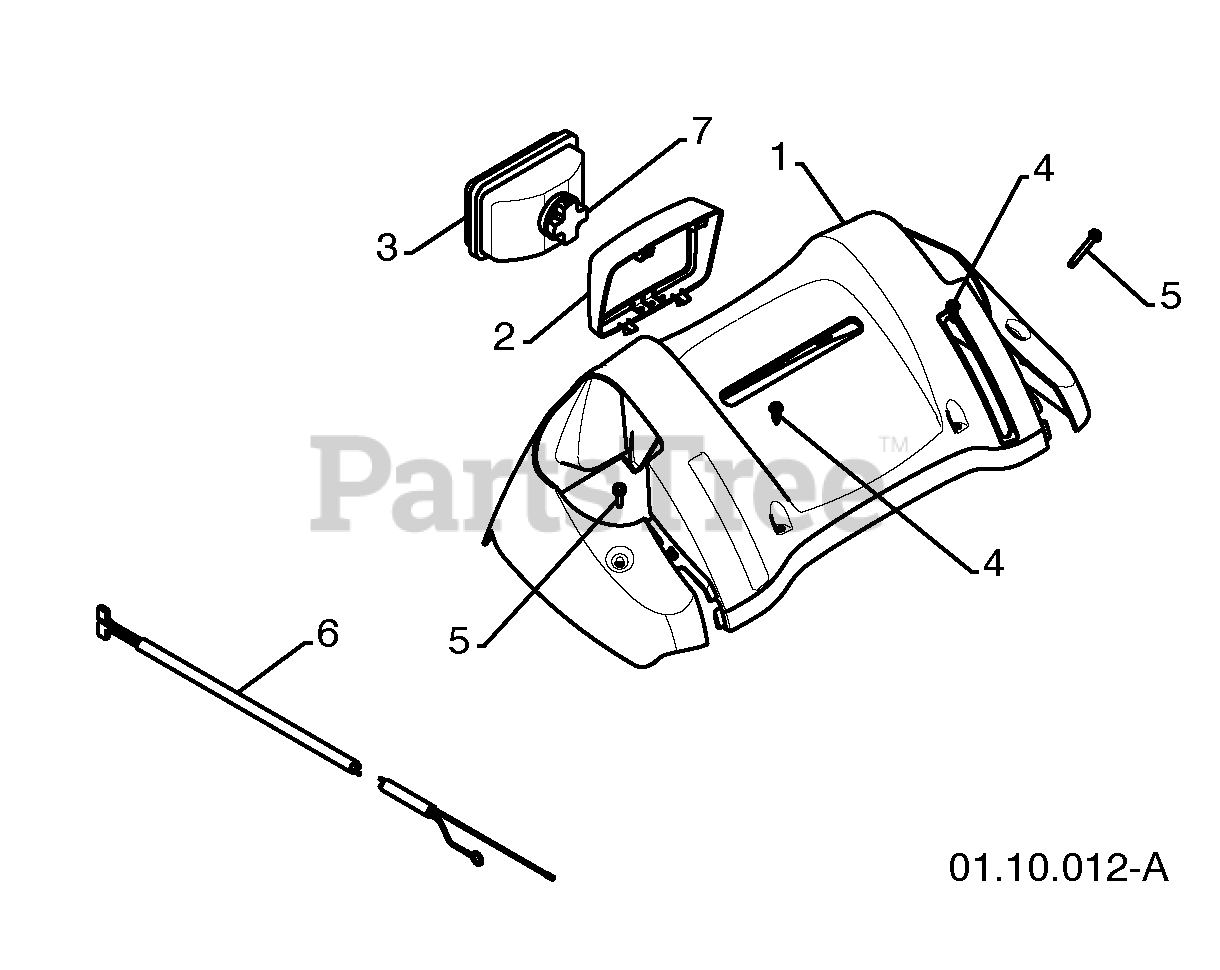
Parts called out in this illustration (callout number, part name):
1	CONSOLE PANEL GRAY
2	HEADLIGHT BEZEL GRAY
3	FLOOD HEADLIGHT
4	SHOULDER SCREW 10-24 X 0.625
5	SCREW 10-24 X 1.25
6	WIRE HARNESS
